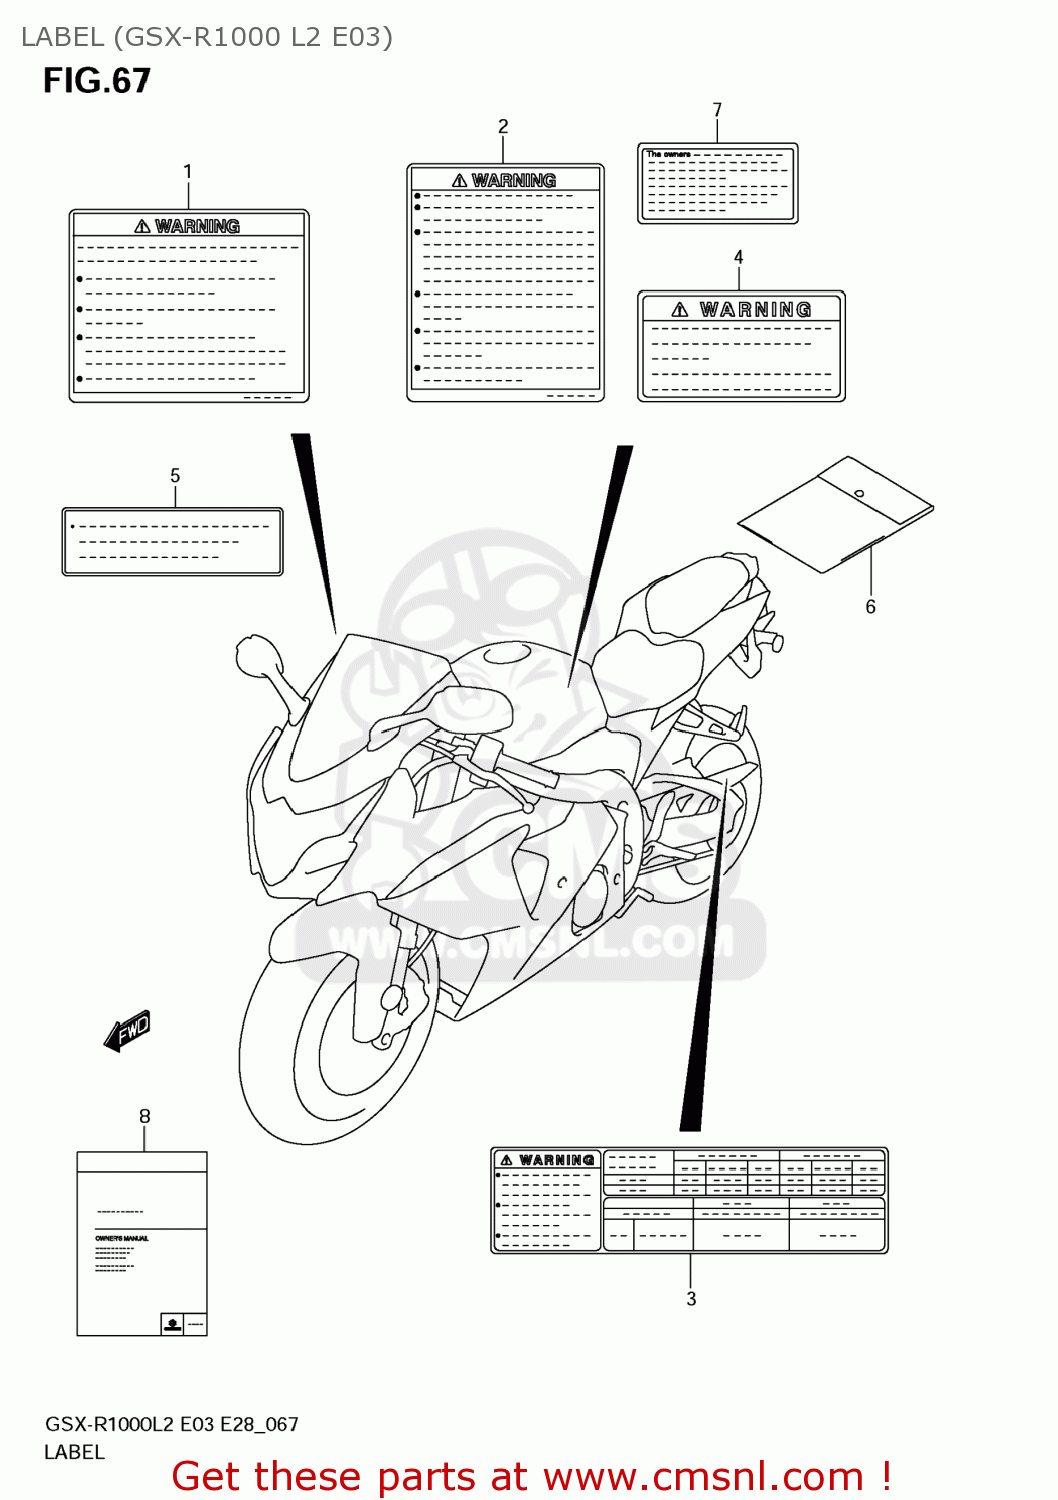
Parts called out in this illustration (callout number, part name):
1	LABEL,GENERAL WARNING
2	LABEL,SCREEN
3	LABEL,TIRE INFORMATION
4	LABEL,WARNING STEERING
5	LABEL,FUEL INFORMATION
6	BAG,OWNER'S MANUAL
7	LABEL,MANUAL NOTICE
8	MANUAL,OWNER'S
